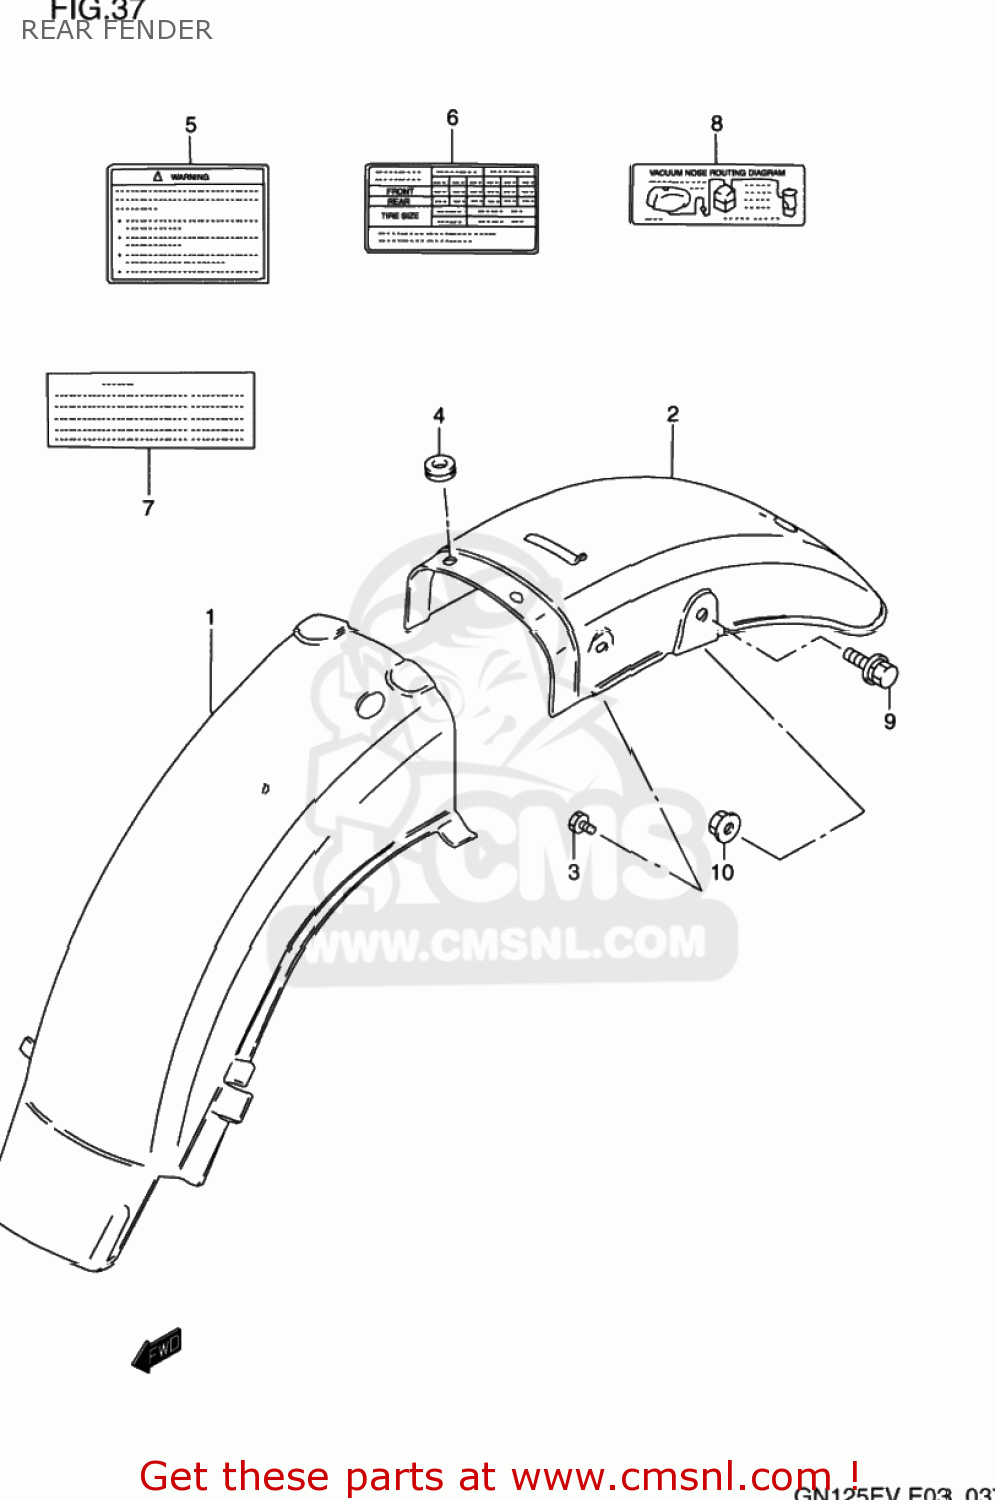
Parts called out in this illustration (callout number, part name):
1	BODY,FR
2	FENDER,REAR FENDER,REAR
3	BOLT
4	CUSHION
5	LABEL (WARNING SAFETY),E
6	LABEL (TIRE AIR PRESSURE)
7	LABEL (MANUAL NOTICE)
8	LABEL (PIPING DIAGRAM)
9	BOLT
10	NUT
